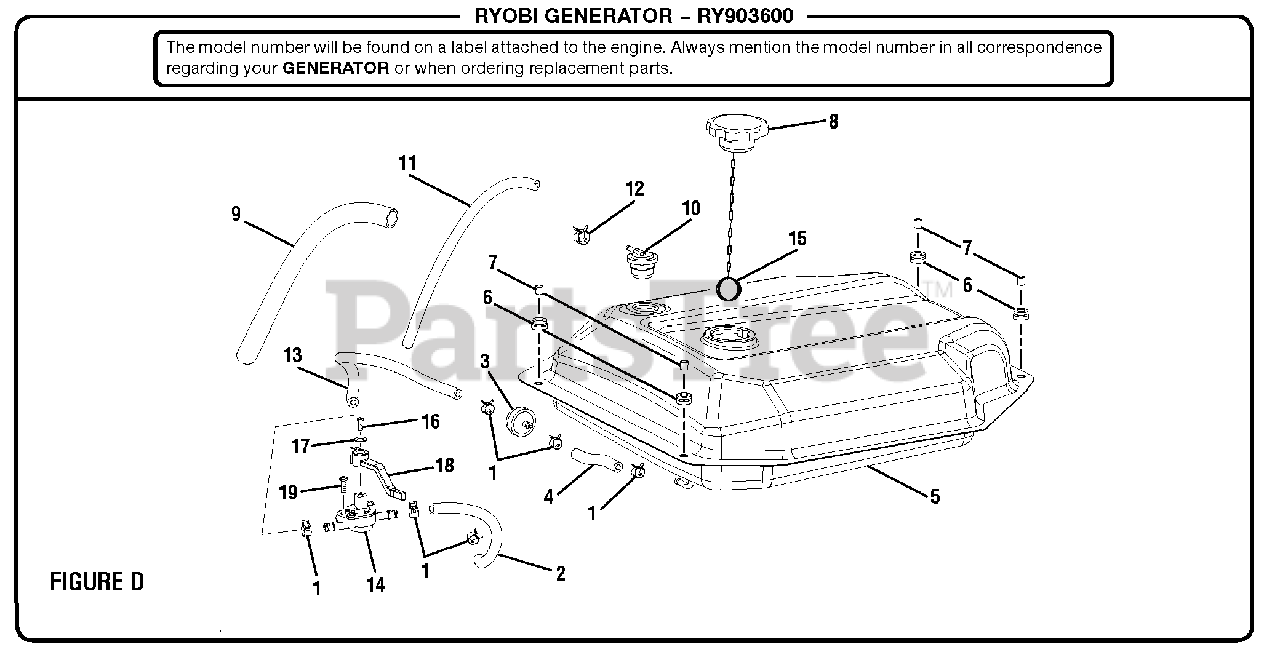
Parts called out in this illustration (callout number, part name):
1	Fuel Line Clamp (1/2 in.)
2	Fuel Hose (175 mm)
3	Fuel Filter Inline (1/4 in.)
4	Fuel Hose (80 mm)
5	Fuel Tank
9	Fuel Hose Cover (200 mm)
10	Vapor Vent
11	Vapor Hose
12	Fuel Line Clamp (7/16 in.)
13	Fuel Hose (300 mm)
14	Fuel Valve
15	Ring Clip
16	Bolt (M4 x 10 mm, Pan Hd.)
17	Washer (ID4.3 x OD10 x 0.9t)
18	Control Lever
19	Screw (M6 x 10 mm, Pan Hd.)
